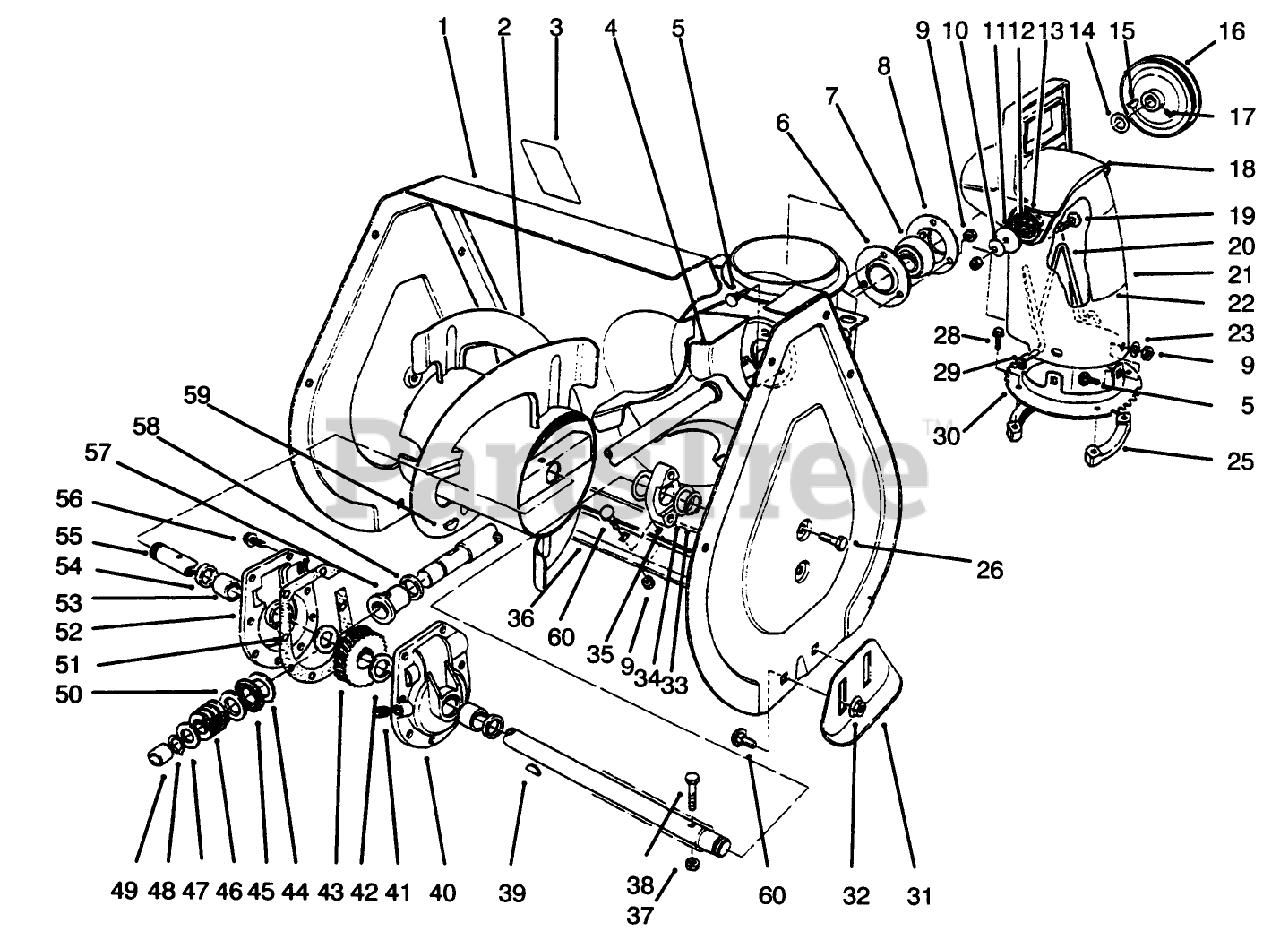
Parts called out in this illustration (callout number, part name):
1	ASM - AUGER HSG W/DECAL
5	SCREW-CARR
6	Flange-Bearing Front
7	BEARING-BALL
8	Flange-Bearing Rear
9	NUT-LOCK, NI
10	WASHER-BELLEVILLE
11	WASHER-FLAT
12	PLATE-FRICTION
13	WASHER-RUBBER
14	WASHER
15	KEY-WOODRUFF
16	PULLEY
17	SCREW-SET, SQH
18	CHUTE-DEFLECTOR
19	SCREW-CARR
20	WIRE-CHUTE
23	WASHER-PLAIN
25	RING-CHUTE, RETAINER
26	SCREW-HWHTF
28	SCREW-SPECIAL
29	NUT-PUSH
32	NUT-HF
33	RING-RETAINING
34	WASHER
37	NUT-LOCK, NI
38	SCREW-HH
39	KEY-WOODRUFF
40	LH BUSHING CASE ASM
41	PLUG-PIPE, SQH
42	WASHER-THRUST
43	GEAR-WORM, 27T
44	WASHER-THRUST
45	BEARING-THRUST
47	WASHER-THRUST
48	RING-SNAP
49	BUSHING
50	WASHER-THRUST
51	GASKET-CASE, GEAR
52	RH BUSHING CASE ASM
53	BUSHING
54	SEAL-OIL
55	AUGER SHAFT
56	SCREW-TAPTITE
57	BUSHING-INPUT
58	RING-QUAD
59	KEY-WOODRUFF
60	BOLT-CARR
